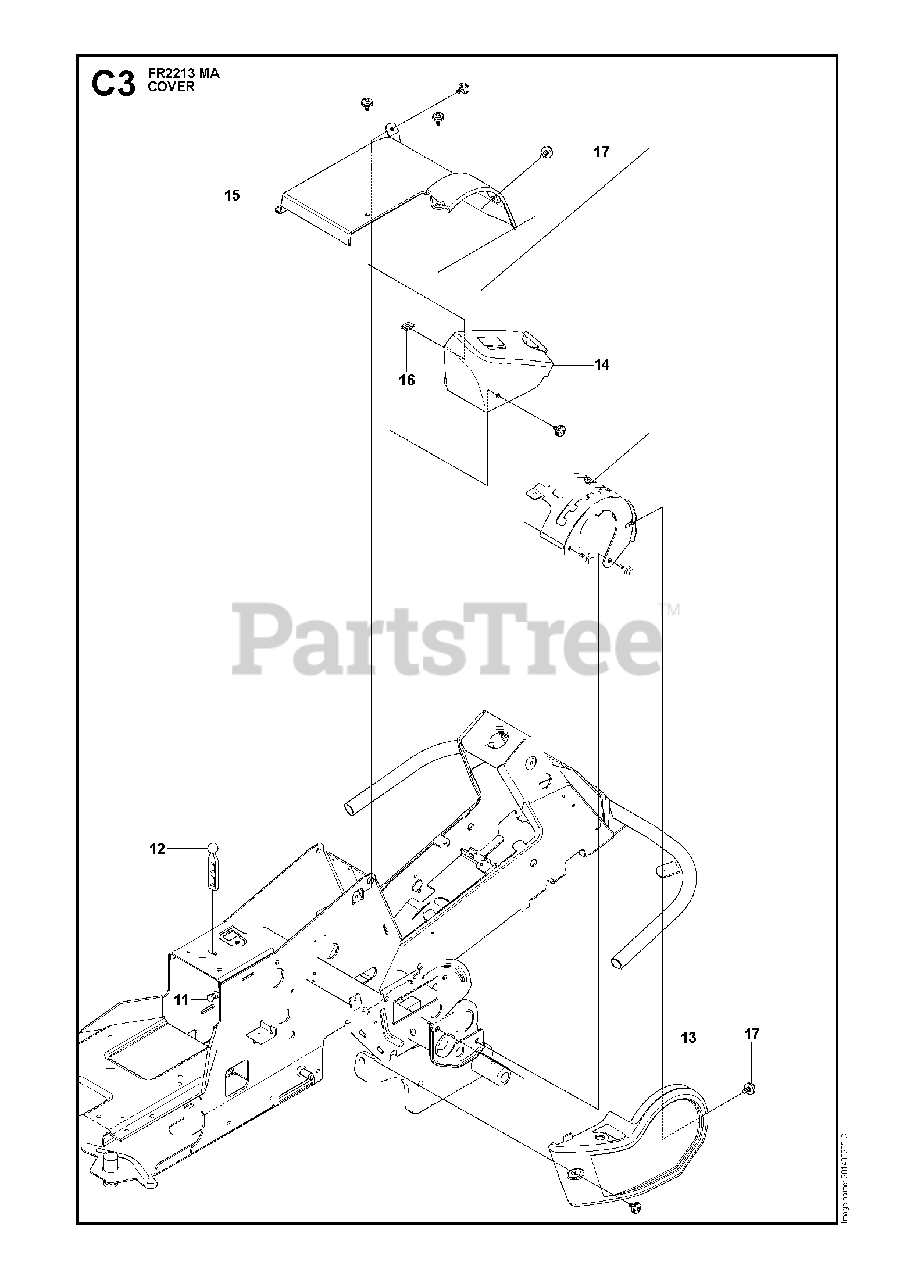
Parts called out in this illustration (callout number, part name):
5	SCREW
9	RIVET
11	BUTTON
12	SUPPORT STRAP
16	NUT
17	SCREW
19	SCREW
21	MAT
22	SCREW
24	SCREW
27	BOLT
28	WASHER
